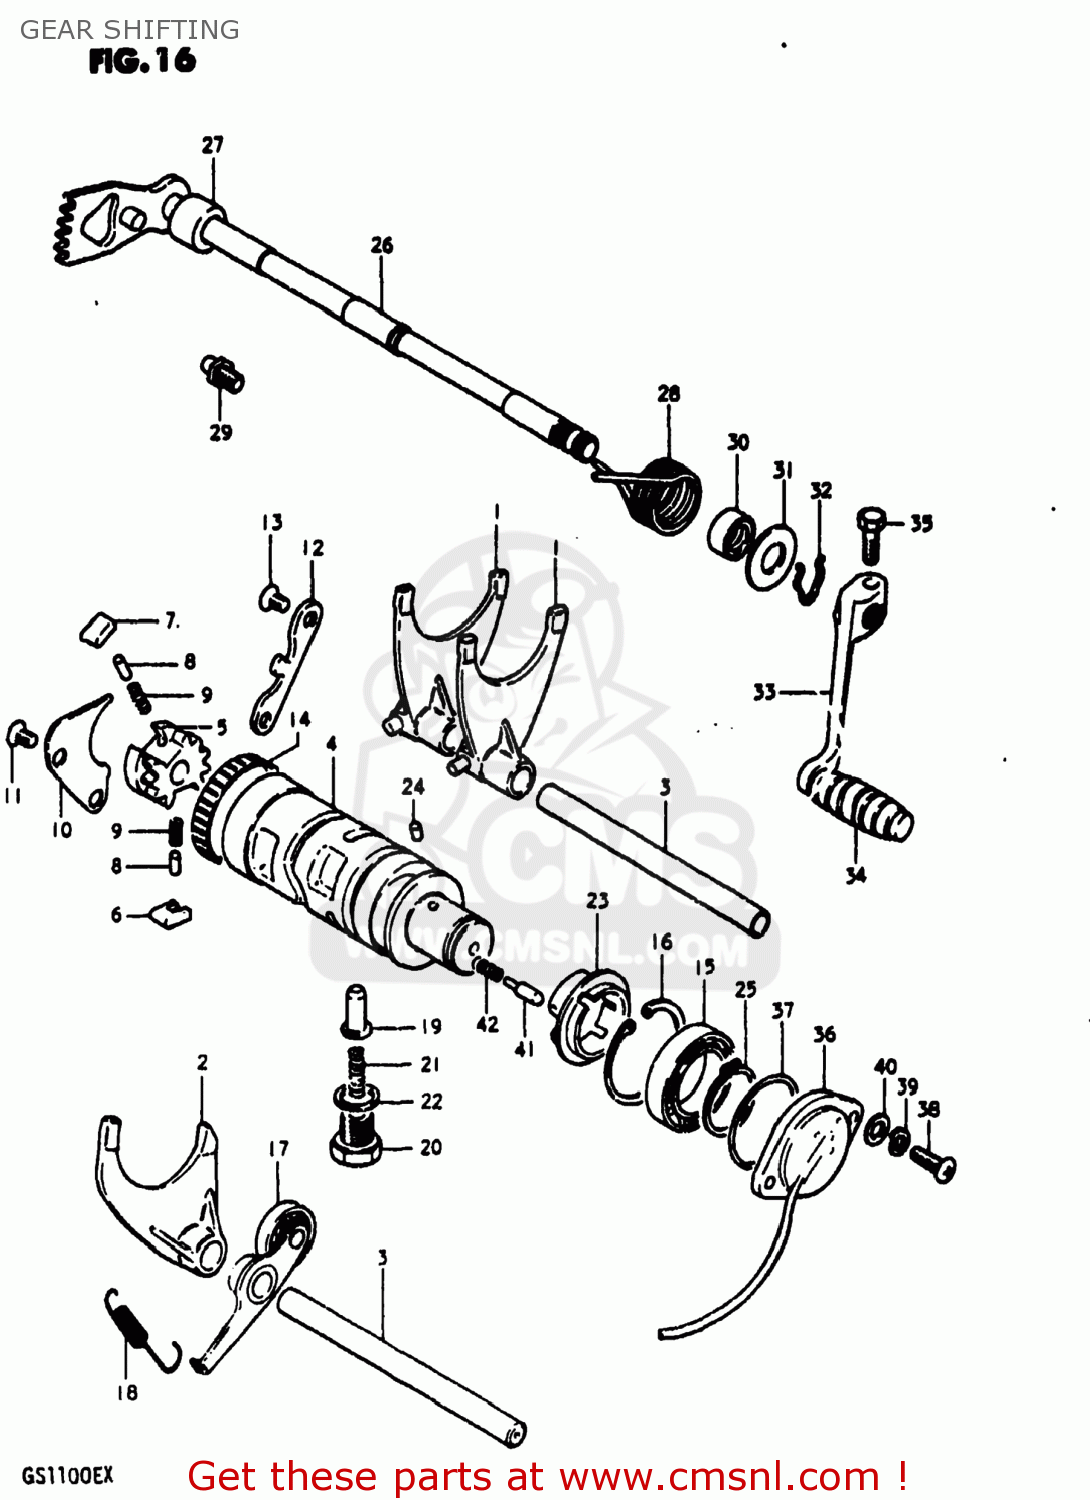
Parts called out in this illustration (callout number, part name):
1	FORK,GEAR SHIFT NO.1
2	FORK,GEAR SHIFT NO.2
3	SHAFT,GEAR SHIFT FORK
4	CAM,GEAR SHIFT
5	RETAINER,GEAR SHIFT CAM
6	PAWL,GEAR SHIFT NO.1
7	PAWL,GEAR SHIFT NO.2
8	PIN(5X8)
9	SPRING
10	LIFTER,GEAR SHIFT PAWL
11	SCREW
12	GUIDE,GEAR SHIFT CAM
13	SCREW
14	BEARING(43X49X12)
15	BALL BEARING
16	CIRCLIP
17	STOPPER,GEAR SHIFTING
18	SPRING
19	STOPPER,GEAR SHIFT CAM NO.2
20	HOLDER,GEAR SHIFT CAM STOP SPR
21	SPRING
22	GASKET(14X19.2X2) (NAS)
23	PLATE,GEAR SHIFT CAM STOPPER
24	PIN 4X6
25	CIRCLIP
26	SHAFT,GEAR SHIFT
27	SPACER(12X20X15.3)
28	SPRING
29	STOPPER,GEAR SHIFT CAM
30	OIL SEAL
31	WASHER (12.5X27X1.6)
32	SPRING,RETAINER
33	LEVER ASSY,GEAR SHIFT
34	RUBBER,GEAR SHIFT PEDAL
35	BOLT
36	BODY, SHIFTING SWITCH
37	O RING(D:2.4,ID:36.5)
38	SCREW
39	LOCK WASHER
40	WASHER
41	PIN(5X15.5)
42	SPRING
